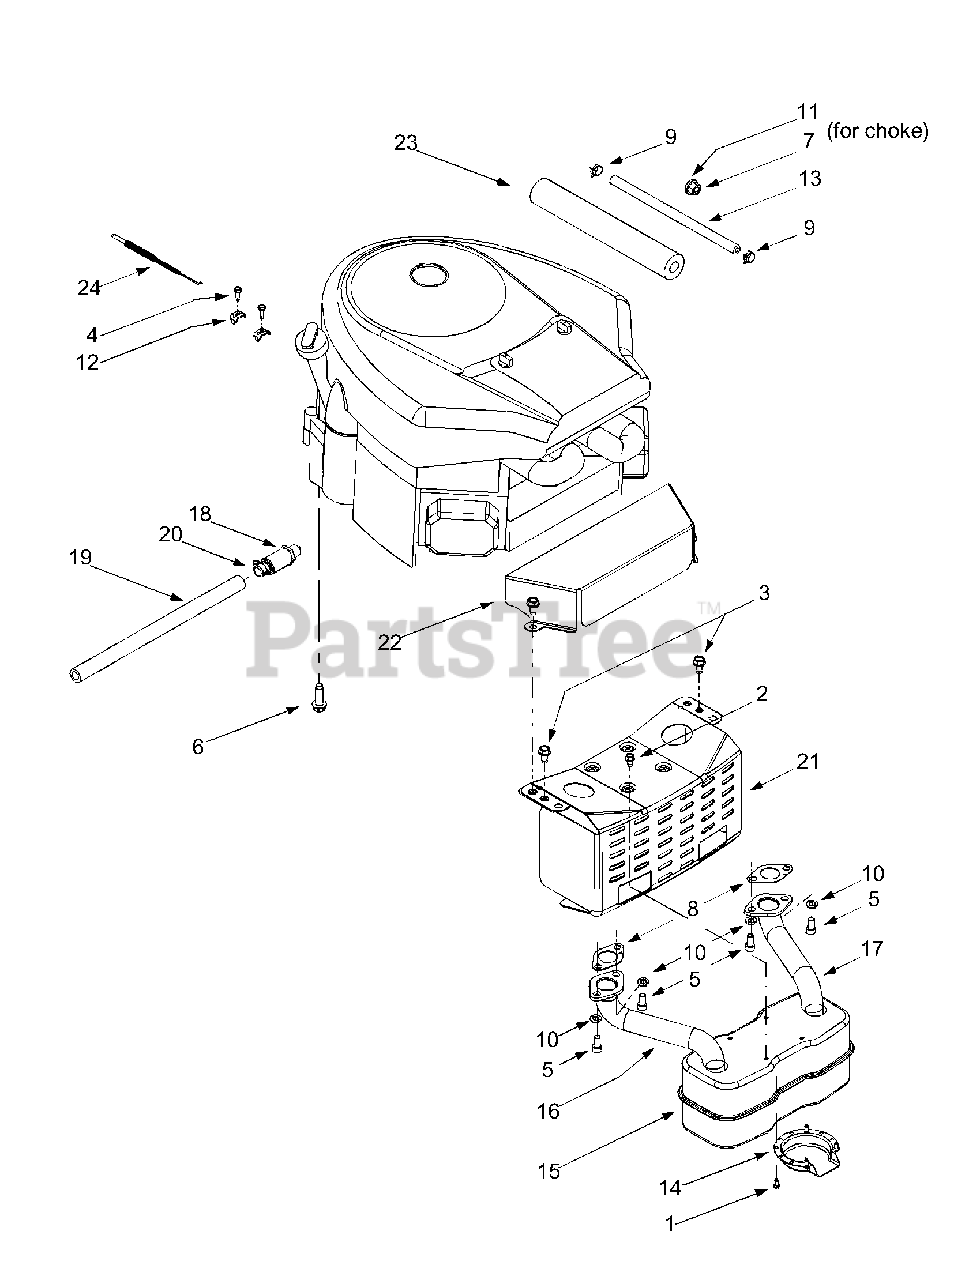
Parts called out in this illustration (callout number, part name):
1	Self-tapping Screw, #8-18 x .5
2	Self-tapping Screw, 1/4-20 x .5
3	AB Screw, 5/16-12 x .75
4	Screw, #10-32 x .625
5	Socket Cap Screw, 5/16-18 x .625
6	Self-tapping Screw, 3/8-16 x 1.25
7	Hex Nut, 3/8-16
8	Exhaust Gasket
9	Hose Clamp
10	Lock Washer, 5/16
11	Flat Washer
12	Casing Clamp
13	Fuel Line Hose
14	Muffler Deflector
15	Muffler, Twin Inlet
16	RH Exhaust Pipe
17	LH Exhaust Pipe
18	Oil Drain Valve
19	Oil Drain Hose
20	Oil Drain Cap
22	Engine Heat Shield
23	Foam (fits over fuel line)
24	Throttle Cable
